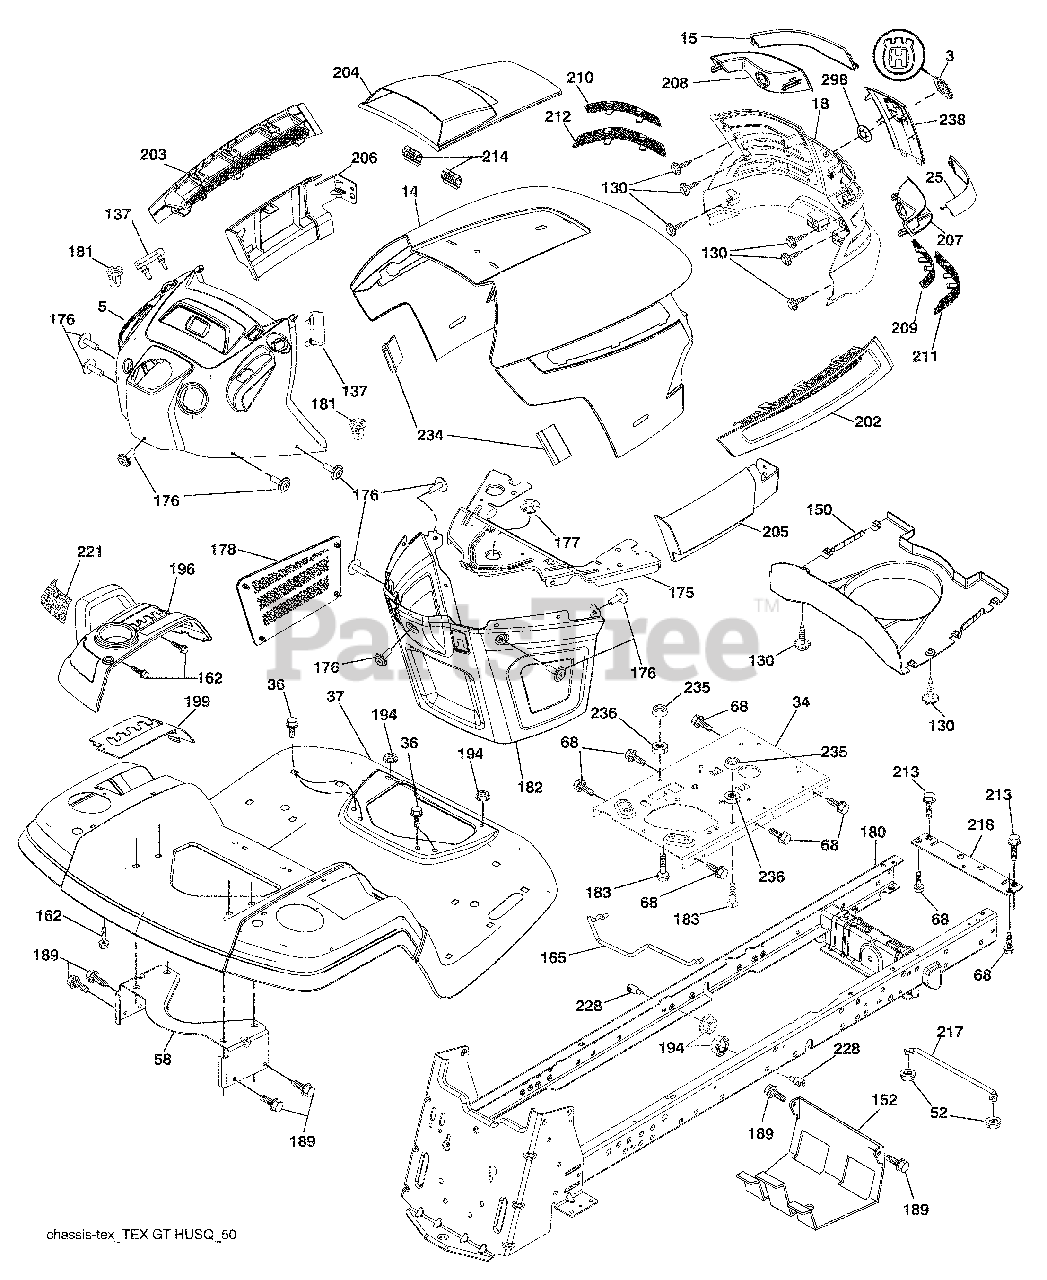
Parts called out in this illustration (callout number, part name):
3	Logo
14	Hood
34	Plate Engine
36	Screw 5/16-18 x 3/4
37	Fender
52	Nut Crown Lock 5/16-18
58	Bracket Fender
68	Screw 5/16-18 x 1/2
130	Screw #10 x 0.750 BOS Thread
137	Bumper Dash
150	Duct Heat Hood
152	Shield Browning/Debris
161	Console Fuel Window
162	Screw Hex Wsh Hi-Lo 1/4 x 1/2
165	Bracket Support Tank
175	Crossmember
176	Screw 10-24 x 5/8 Wshd Qdrx
177	Bushing Steering
178	Cargo Asm. Net
180	Chassis
181	Bushing Mtg. Fender Crgo.
182	Dash Lower
183	Bolt Fin Hex 5/16-18 unc x 1-1/4
189	Screw 5/16-18 x 3/4
194	Nut Lock Hex Flange 5/16-18
196	Console Asm. Deck Lift
199	Plate Deck Lift
202	Vent Side Hood RH
203	Vent Side Hood LH
204	Vent Asm Hood Top
205	Skirt Hood Side RH
206	Skirt Hood Side LH
209	Insert Hex Top RH
210	Insert Hex Top LH
211	Insert Hex Bottom RH
212	Insert Hex Bottom LH
213	Bolt Hex Hd 5/16-18 unc x 3/4
214	Clip Retainer
218	X-Piece Hood Stop
221	Reflector LH
228	Stud Fastener
234	Bumper Hood
235	Spacer Fender
236	Nut Center Lock 5/16-18 unc
